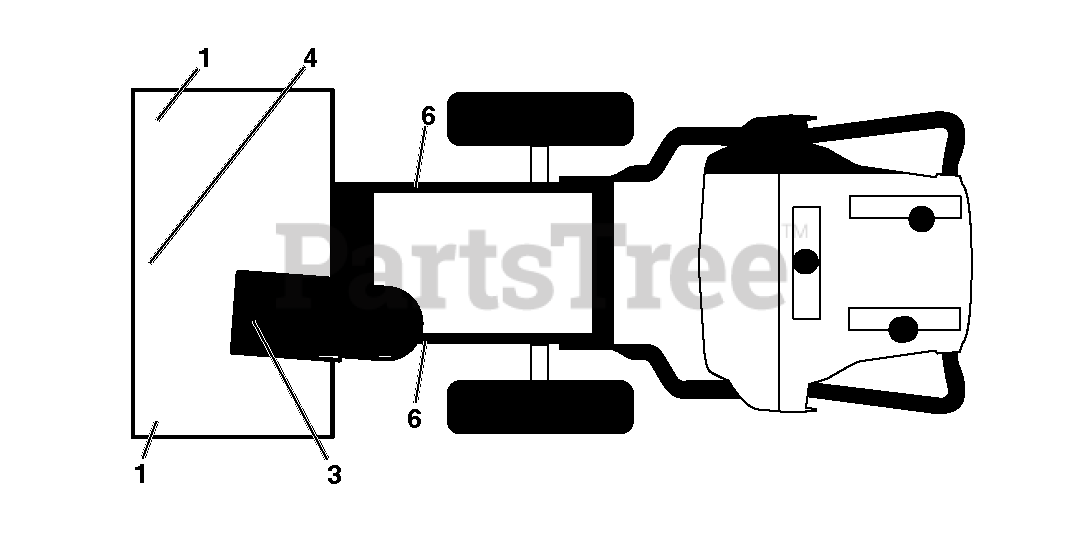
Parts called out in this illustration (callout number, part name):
1	DECAL.AUGER.SAFETY.
3	DECAL.CHUTE.SAFETY.EU/SC.17
4	DECAL.AUGER."
6	DECAL.BELT.GUARD.
